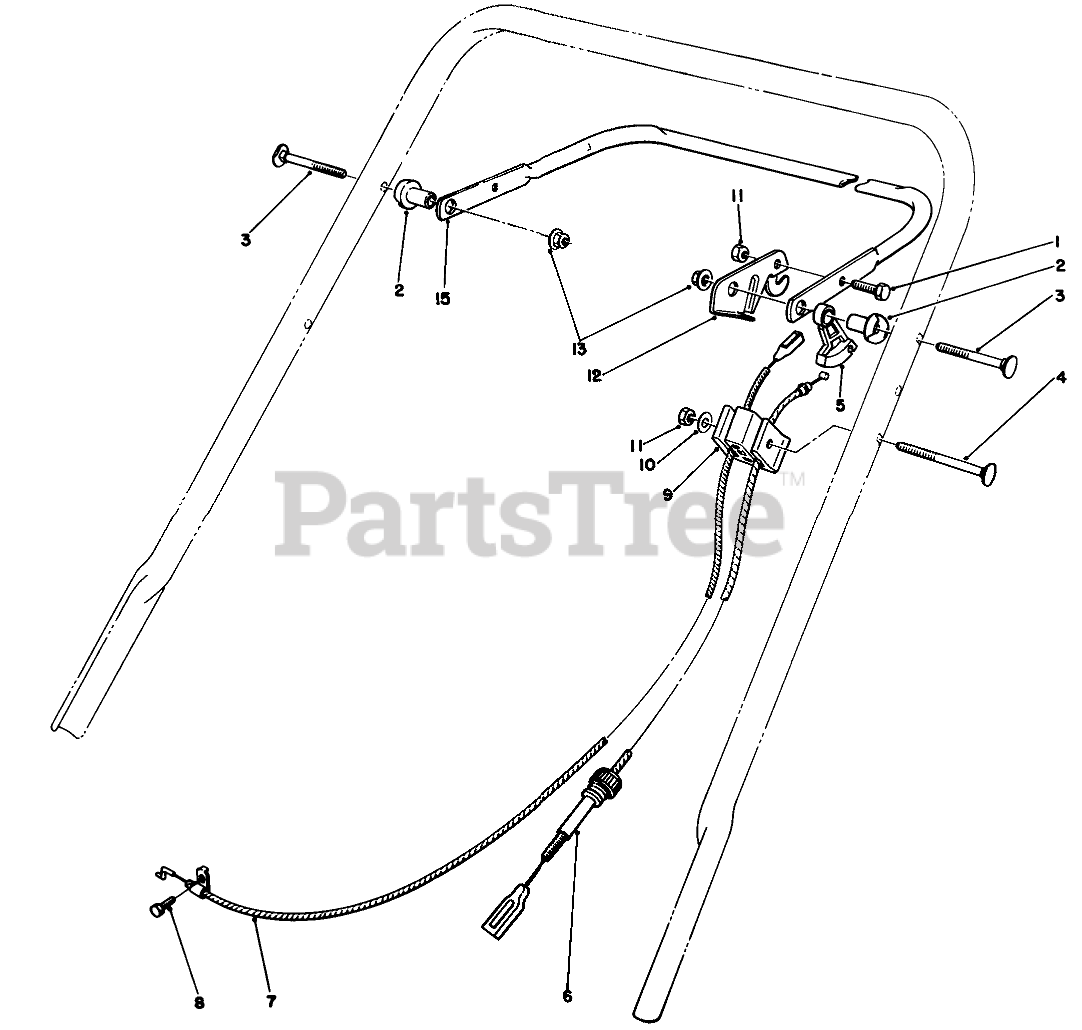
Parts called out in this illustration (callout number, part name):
1	SCREW-HH
2	SPACER-SUPPORT
3	5/16-18 X 2 HNDLE SCREW
4	HANDLE SCREW
5	LEVER-TRACTION
6	CABLE-TRACTION
7	BRAKE CABLE
8	SCREW-HH
9	SUPPORT-CABLE
10	WASHER-FLAT
11	NUT-LOCK, NI
12	LEVER-CONTROL
13	NUT-LOCK, NI
15	Bar-Control
